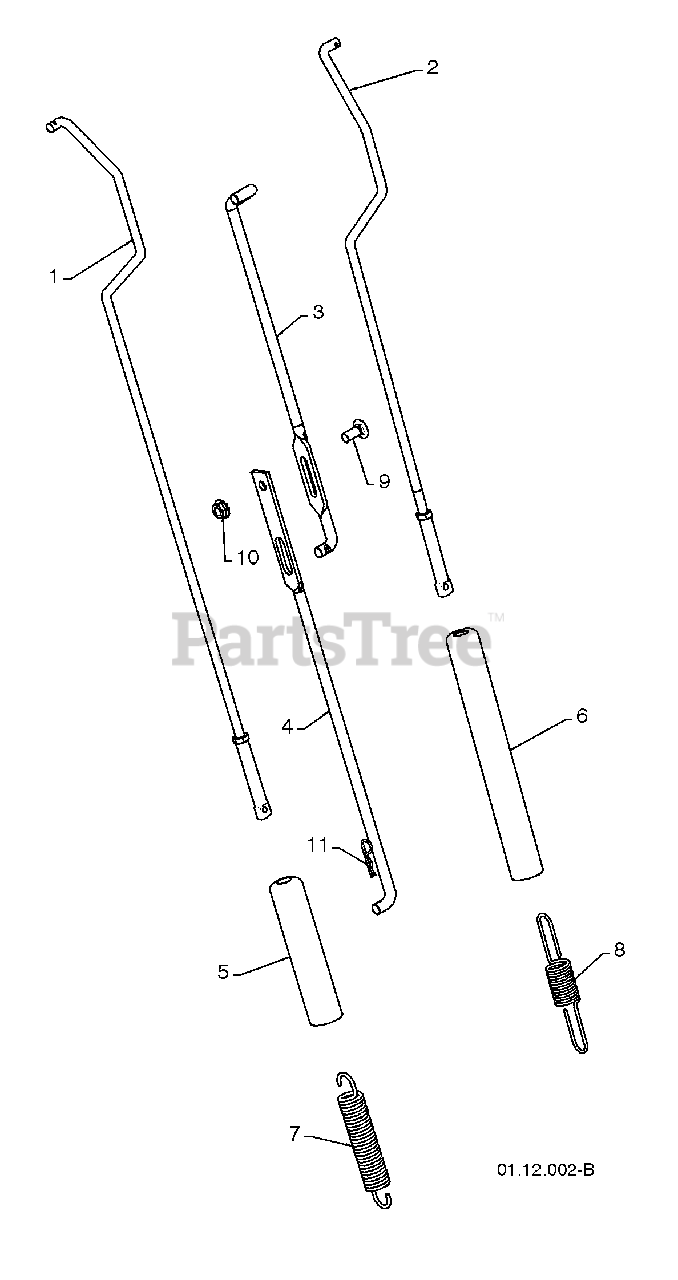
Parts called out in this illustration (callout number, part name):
1	IMPELLER ROD ASSEMBLY
2	TRACTION ROD ASSEMBLY
3	SHIFTER ROD TOP
4	SHIFTER ROD BOTTOM
5	SPRING SLEEVE
6	SPRING SLEEVE
7	IMPELLER SPRING
8	TRACTION SPRING
9	CARRIAGE BOLT 5/16-18 X .750
10	NUT 5/16-18
